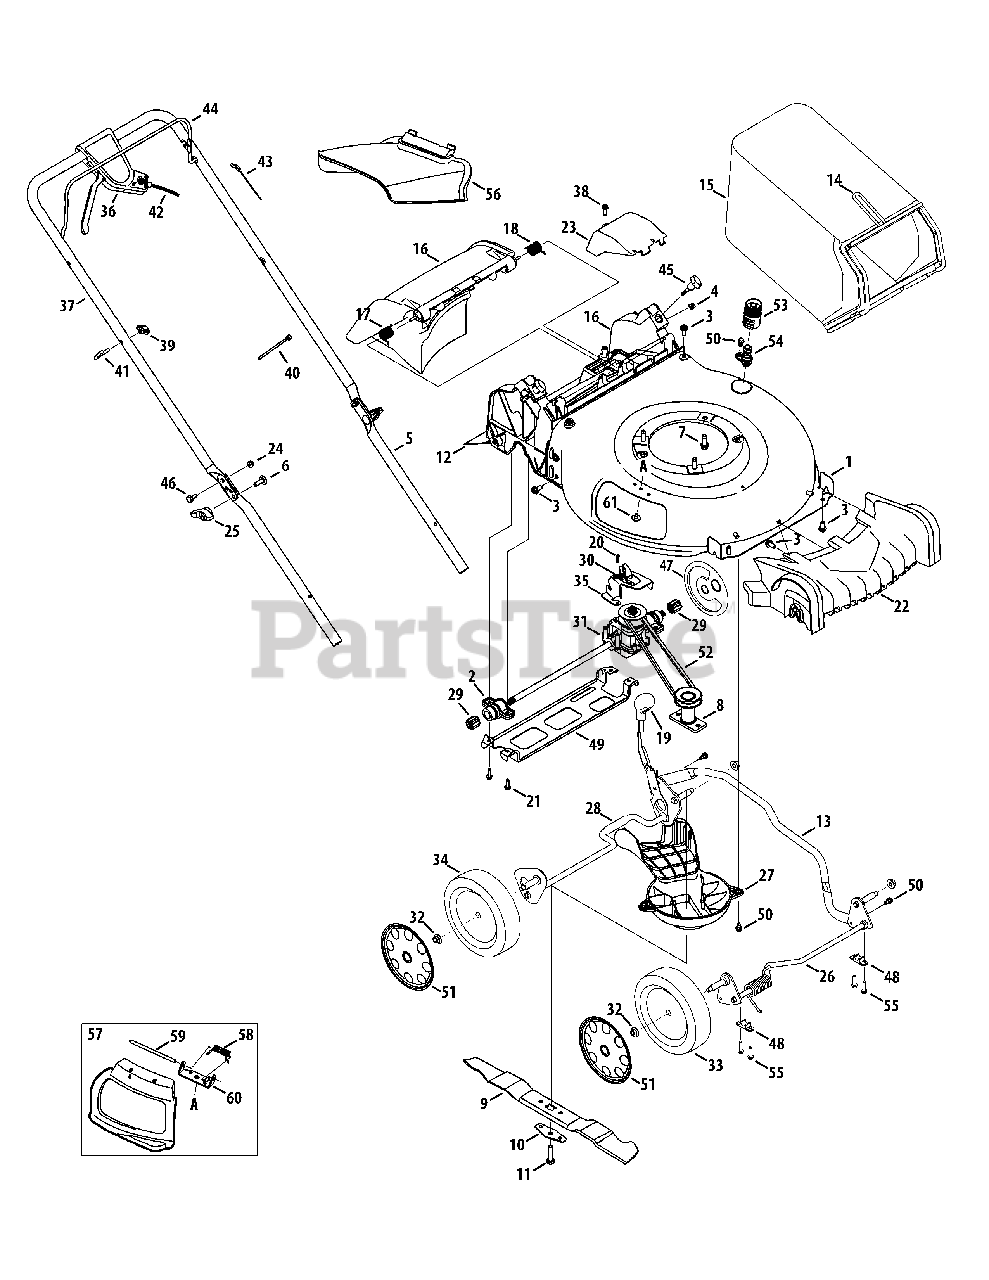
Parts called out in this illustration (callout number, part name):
1	Deck, 21"
2	Bearing Assembly
3	Screw, 5/16-14 x .750
4	Nut, Sq., 1/4-20
5	Lower Handle
6	Carriage Screw ,5/16-18
7	Screw, 3/8-16 x 1.00
8	Blade Adapter
9	Mulching Blade
10	Blade Bell Support
11	Screw, 3/8-24 x 1.50
12	Trailing Shield
13	Cross Bracket
14	Grass Catcher Frame
16	Rear Discharge Door Assembly
17	Torsion Spring - RH
18	Torsion Spring - LH
19	Adjustment Lever Knob
20	Screw, Hex Washer, .159 x .43
21	Screw, 1/4-15 x 1.25
22	Front Cover
23	Transmission Cover
24	Nut, Flange Lock, 1/4-20
26	Front Axle Assembly
27	Engine Baffle
28	Rear Axle Assembly
29	Spur Gear, 10T
30	Exten. Spring, 2.405
31	Transmission Assembly
32	Flange Lock Nut, 3/8-16
33	Front Wheel
34	Rear Wheel
35	Transmission Bracket
36	Control Lever Assembly
37	Upper Handle
38	Screw, 1/4-15 x .750
40	Cable Tie
41	Rope Guide
42	Variable Speed Cable
43	Control Cable
44	Blade Control
45	Wing Nut
46	Sldr. Screw, .375 x .126 x 1/4-20
47	Wheel Dust Cover
48	Bushing, Lock, .505 Dia. X .62
49	Rear Support Bracket
50	Screw, Shldr., 1/4-20 x .50
51	Hubcap, 8"
53	Water Nozzle Adapter
54	Water Nozzle
55	Screw, 1/4-15 x 1.000
56	Side Discharge Chute
57	Mulch Plug (Incl. 58-60)
58	Torsion Spring
60	Chute Deflector Bracket
61	Screw, 1/4-20 x .500
